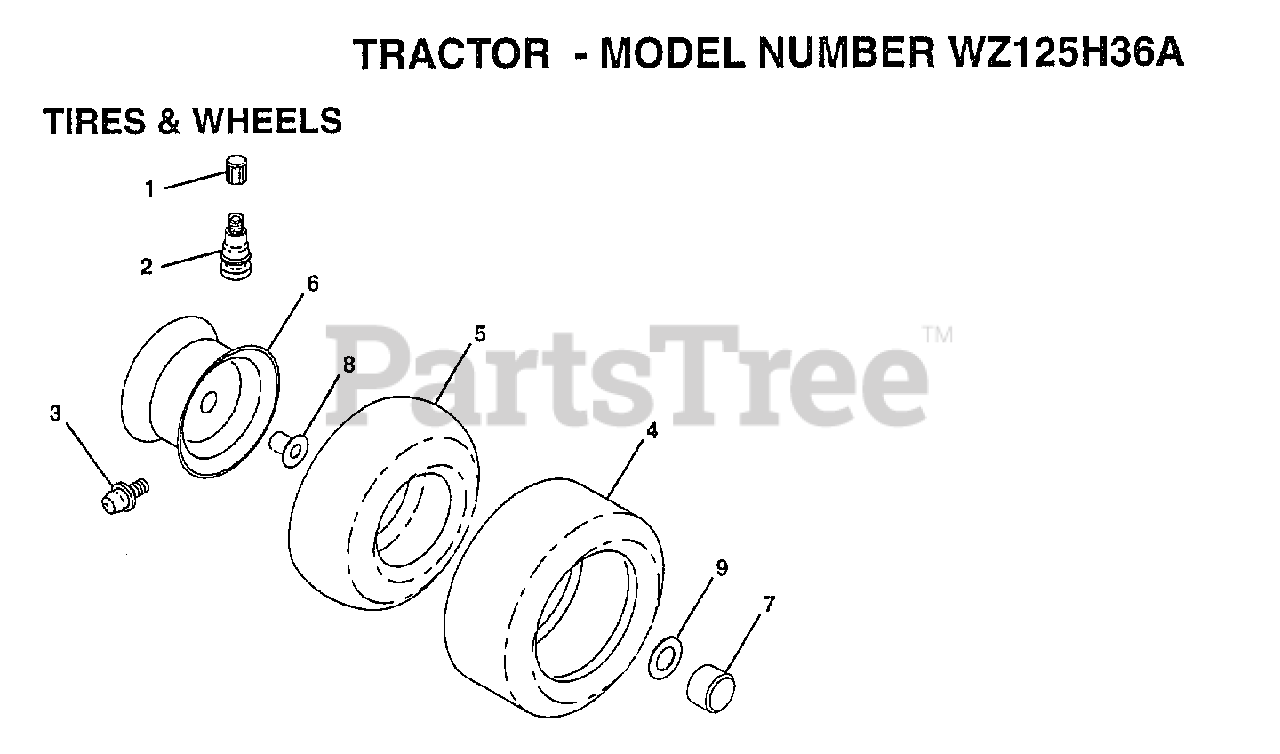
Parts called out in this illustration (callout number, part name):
1	VALVE CAP
2	VALVE STEM LT
3	FITTING LT
5	TUBE.5.3/4.5/6
5	TUBE.16X6.5/7.5-8
6	"RIM FRONT 6"""
6	"RIM ASM REAR 8"""
7	HUB CAP
8	"FLANGE, BEARING"
9	WASHER
